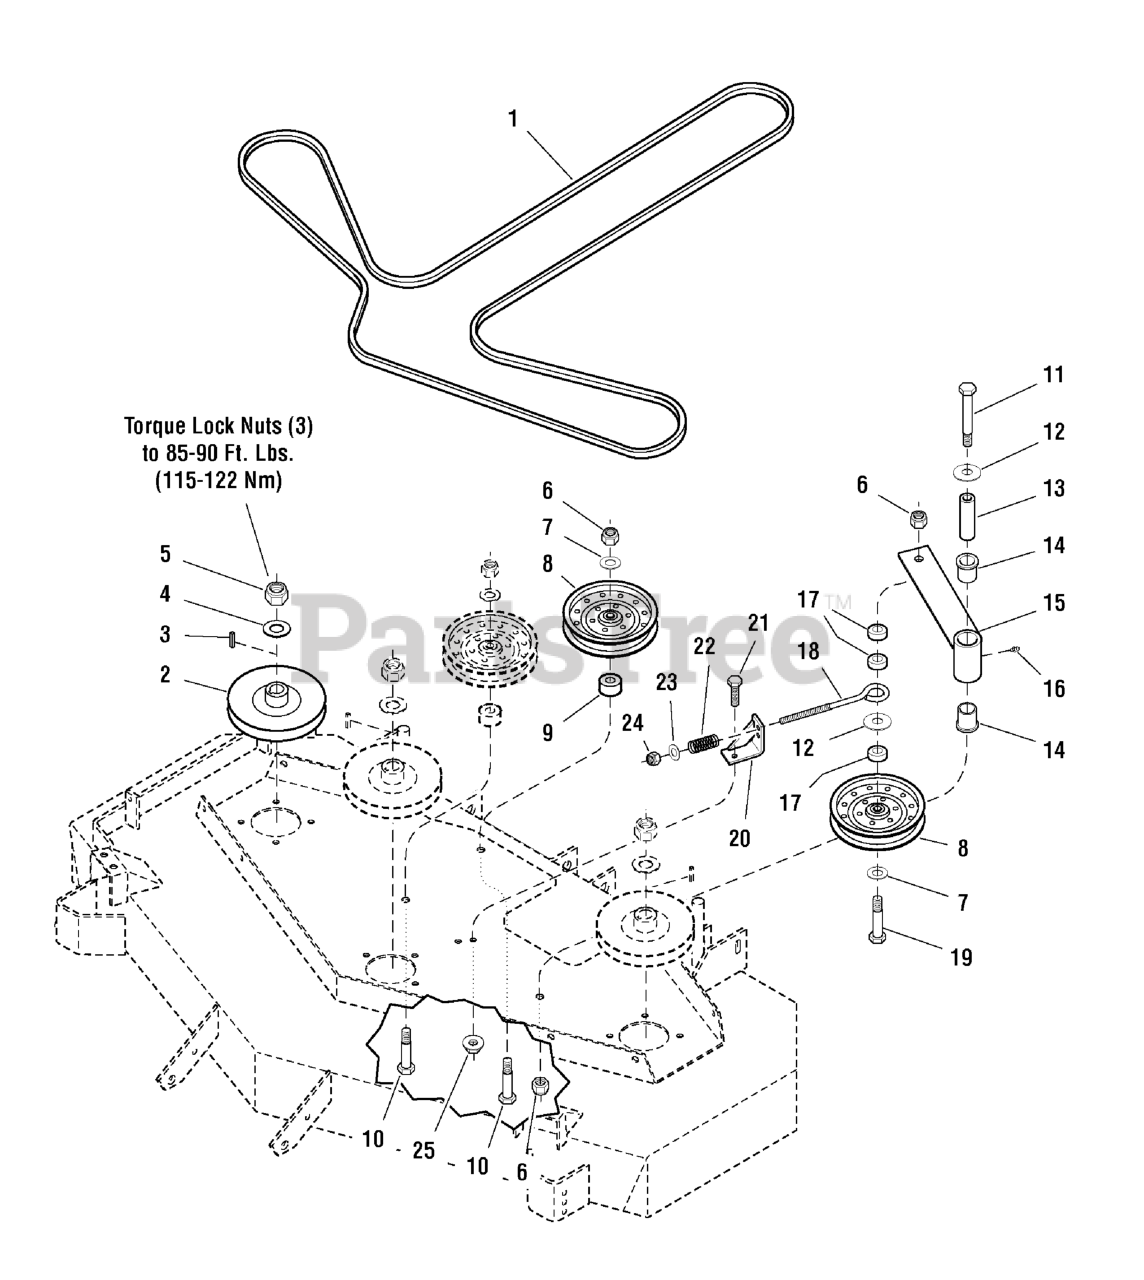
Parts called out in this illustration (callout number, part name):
1	BELT (48" Deck)
1	BELT, 5V, 150.90"EL, ARAMID, WRPD, RC
2	PULLEY, Spindle, Gold
2	PULLEY, 5.540OB X .985ID, SINGLE B-SEC
2	PULLEY, 6.122 OD X .98 BORE
3	KEY, 1/4 SQ. X 1-1/4
4	WASHER, Spring
4	WASHER, 3/4 BELLEVILLE CL/ZC
5	NUT, 5/8-18 Hex Nylon Lock
5	NUT, 3/4-16 Hex
6	NUT, 1/2-13 HEX NYLON LOCK
7	WASHER, 1/2 SAE
9	SPACER, .52 x 1.25 x .70
10	BOLT, 1/2-13 X 3" GD5 CZ
11	BOLT, 1/2-13 x 4-1/2
12	WASHER, 1/2" USS
13	SPACER, .52 x 1.00 x 3.50
14	BUSHING, FLANGE
15	ASSM, IDLER ARM
16	GREASE FITTING
17	SPACER, .52 x 1.00 x .44
18	EYEBOLT, 3/8" x 8"
19	BOLT, 1/2-13 X 3-1/2, HEX HD, GD5, CZ (SV)
20	SPRING ANCHOR
21	BOLT, 3/8-16 X 1" GD5 CZ
22	SPRING, Compression
23	WASHER, 3/8 SAE
24	NUT, 3/8-16 HEX NYLON LOCK
25	NUT, 3/8-16 Hex Serrated Flange
